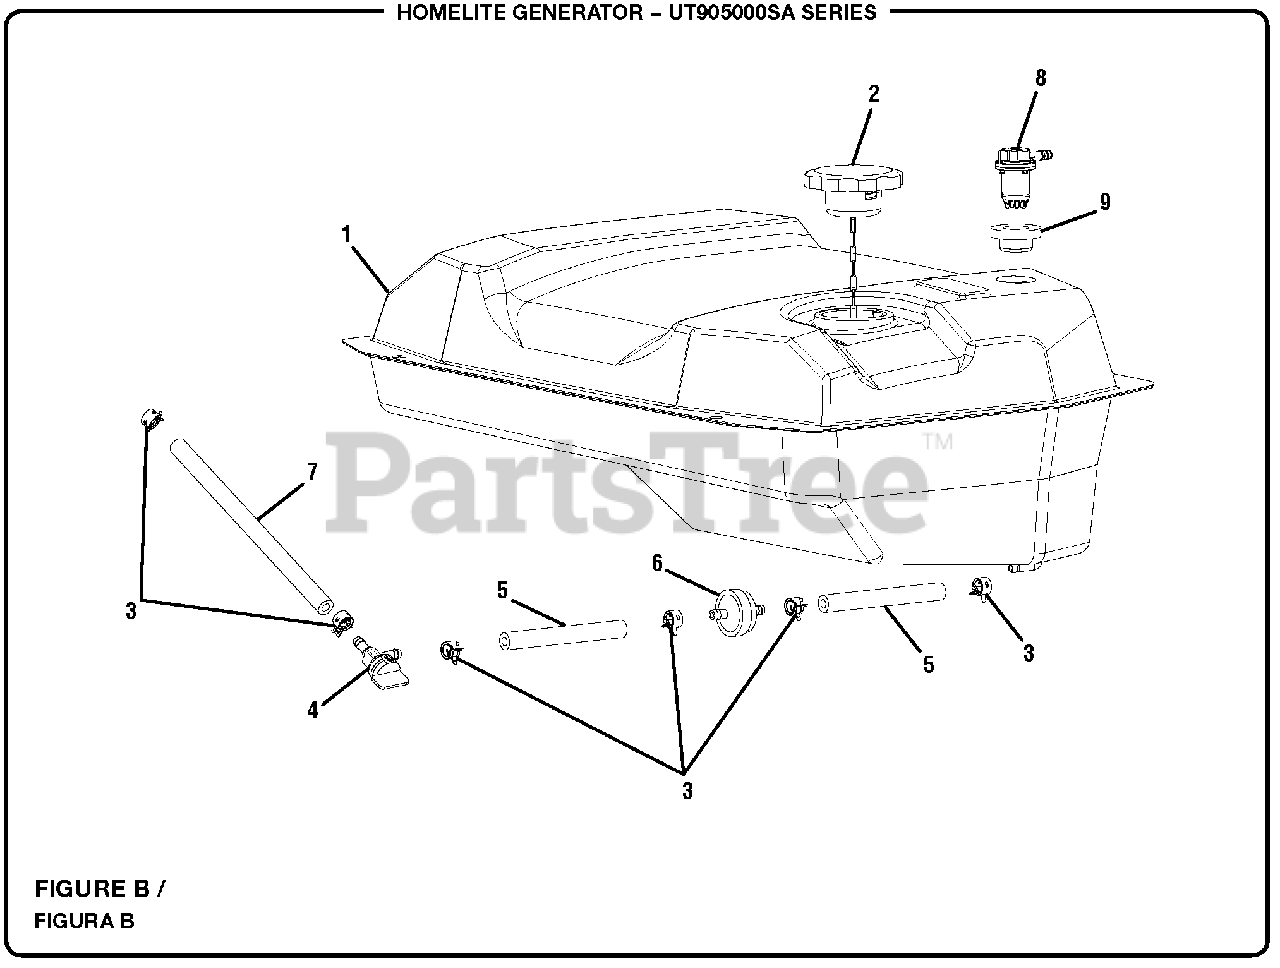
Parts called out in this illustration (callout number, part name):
1	Fuel Tank
2	Fuel Tank Cap
3	Fuel Line Clamp (1/2 in)
4	Fuel Shut Off Valve
5	Fuel Line (64 mm x 105 mm)
6	Fuel Filter
7	Fuel Line (64 mm x 208 mm)
8	Fuel Tank Vent Valve
